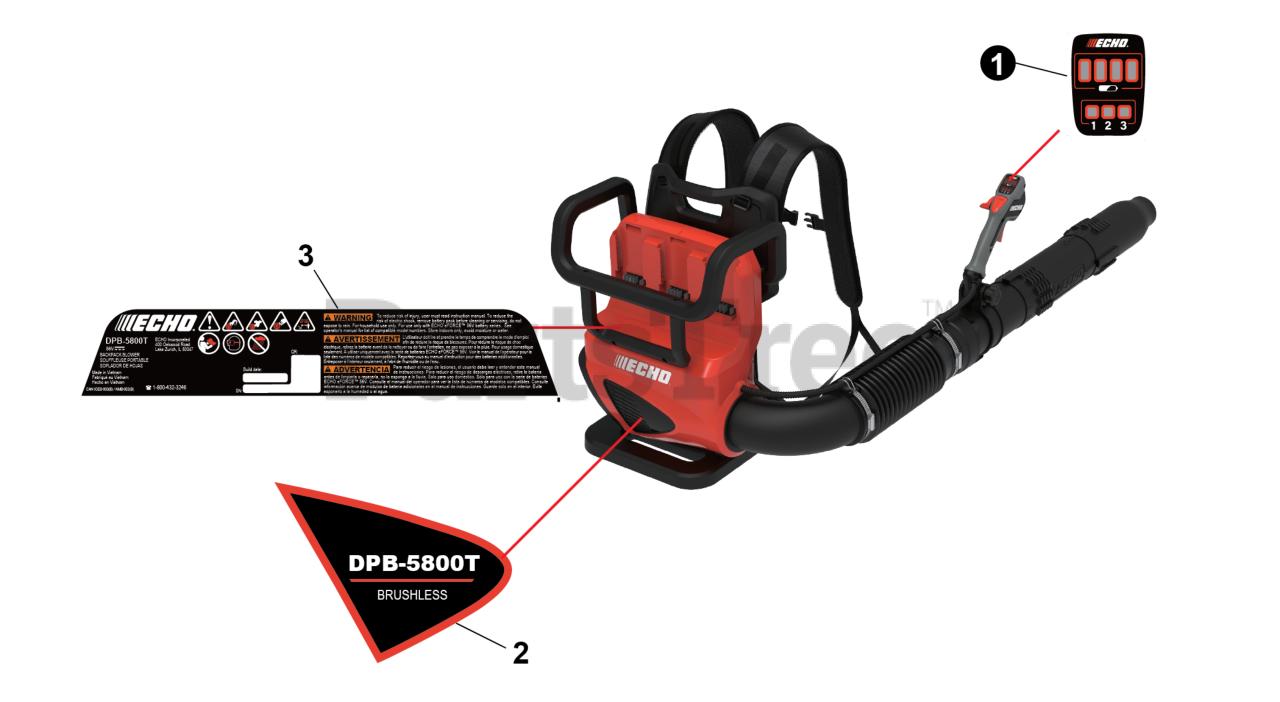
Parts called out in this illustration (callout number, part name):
1	LABEL, LED
2	LABEL, MODEL
3	LABLE,WARNING - VIETNAM
